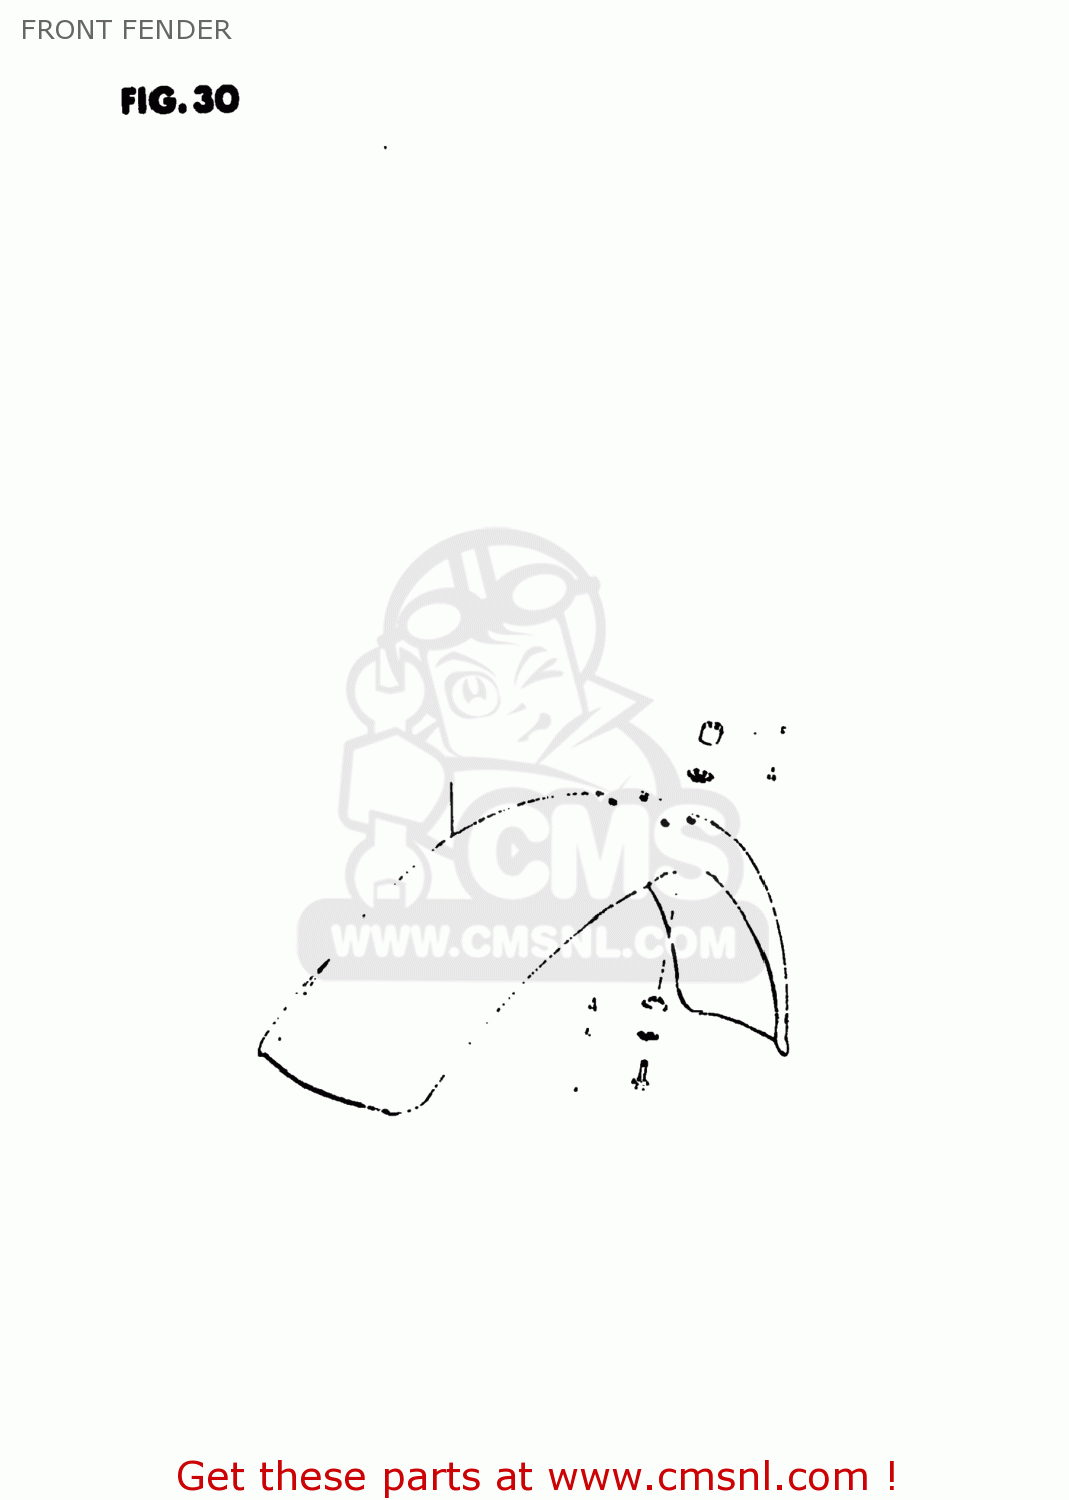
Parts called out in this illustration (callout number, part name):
1	FENDER,FRONT
2	BOLT
3	LOCK WASHER
4	WASHER
5	SPACER (6.8X10X11.5)
